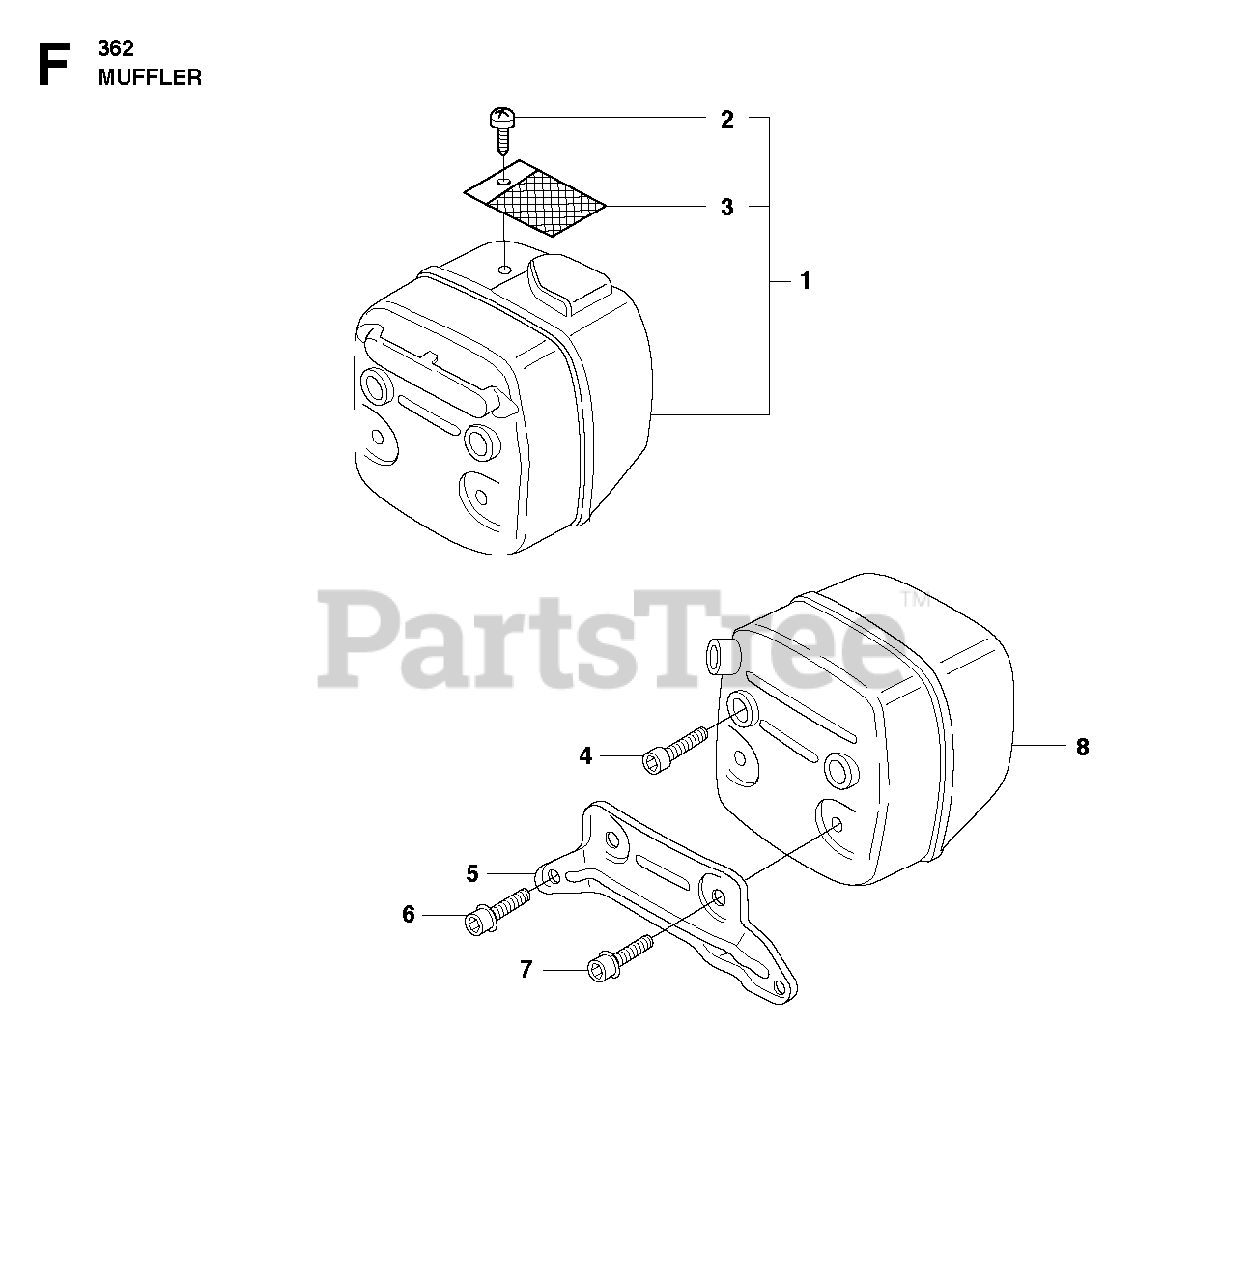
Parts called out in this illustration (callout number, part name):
1	MUFFLER
2	SCREW
3	SCREEN
4	SCREW MC6S 6X20
5	RP SUPPORT
6	SCREW IHSCFM
7	SCREW IHSCFM
8	MUFFLER ASSY
